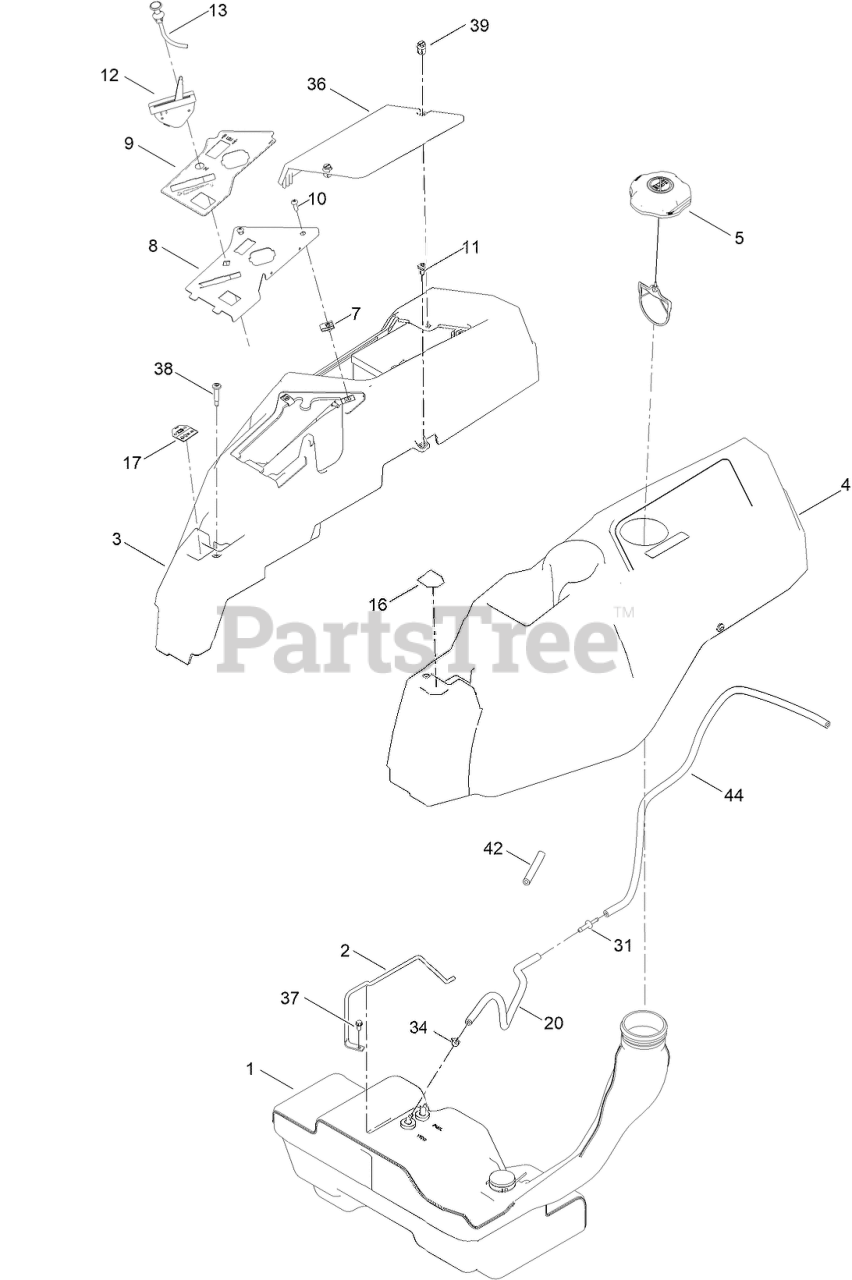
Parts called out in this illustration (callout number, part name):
1	FUEL TANK ASM
2	ROD-HOLD DOWN
3	POD-RH
4	POD-LH
5	CAP-FUEL, RATCHETING
8	PANEL-CONTROL
9	DECAL-PANEL, CONTROL
10	SCREW-PRH
11	SCREW-SHOULDER
12	CABLE-THROTTLE
13	CABLE-CHOKE
16	DECAL-LEVER, CONTROL (LH)
17	DECAL-LEVER, CONTROL (RH)
20	HOSE-FUEL
31	ADAPTOR-ORIFICE
34	CLAMP-HOSE
36	COVER-BATTERY
37	SCREW-HWH
38	SCREW-SHOULDER
39	FASTENER
42	SLEEVE-FUEL LINE PROTECTOR
44	HOSE-FUEL
